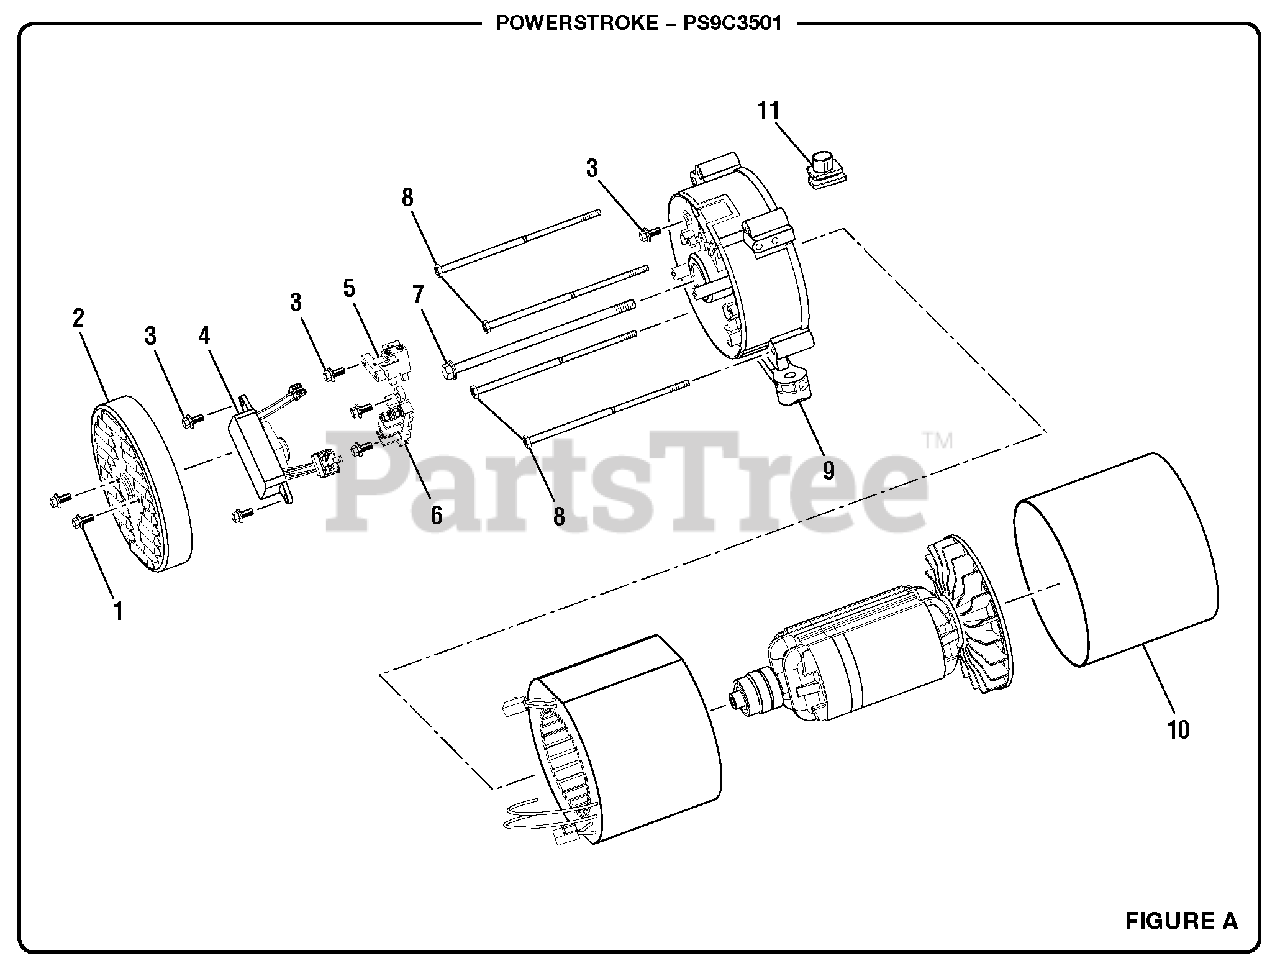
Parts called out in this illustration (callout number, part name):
1	Bolt (M5 x 16 mm, Hex Hd.)
2	Brush Cover
3	Bolt (M5 x 10 mm)
4	Automatic Voltage Regulator
5	Brush Assembly
6	Terminal Block
7	Rotor Bolt
8	Stator Bolt
9	Bearing Housing
10	Generator Head Cover
11	Rubber Boot
